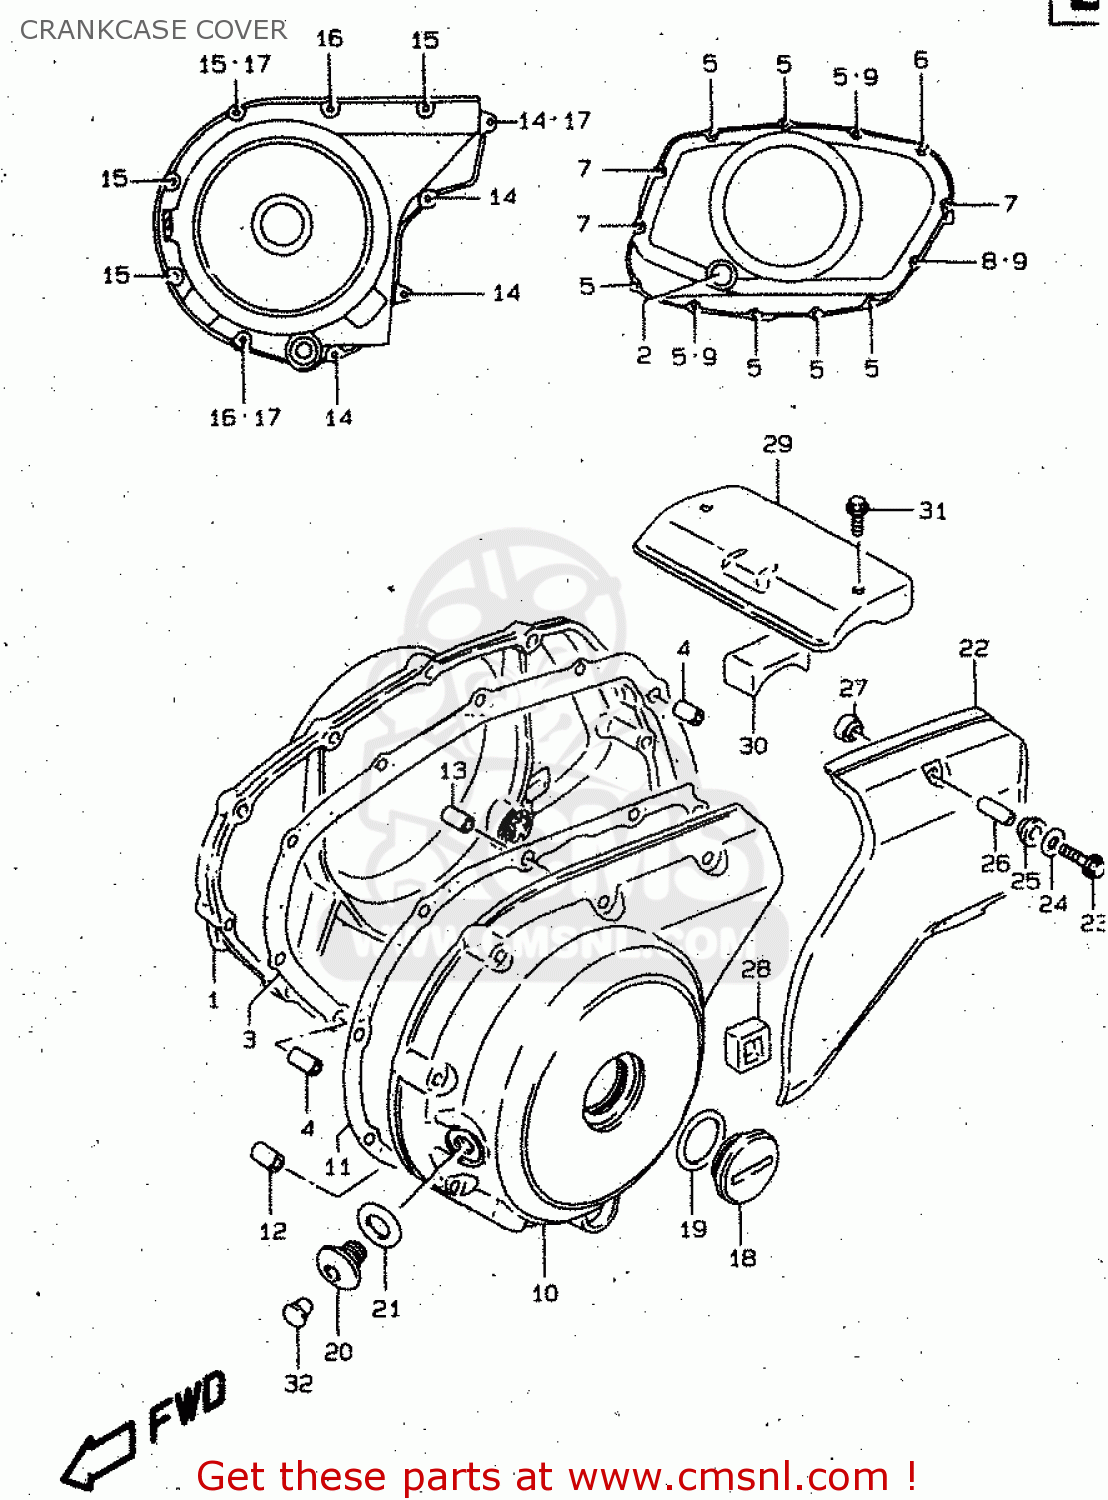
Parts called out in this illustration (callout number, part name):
1	COVER,CLUTCH
2	LENS,OIL LEVEL CHECK
3	GASKET,CLUTCH COVER (NAS)
4	PIN
5	BOLT
6	BOLT
7	BOLT
8	BOLT
9	GASKET(5.8X11X1.2) (NAS)
10	COVER,GENERATOR
11	GASKET,GENERATOR COVER (NAS)
12	PIN(8.4X11X20)
13	PIN
14	BOLT
15	BOLT
16	BOLT
17	GASKET(5.8X11X1.2) (NAS)
18	Chrome Crankshaft Plug
19	O RING(D:3.1,ID:32.7)
20	PLUG,14X12
21	GASKET(13.8X18.8X4.8) (NAS)
22	COVER,SECONDARY GEAR CASE
23	BOLT
24	WASHER(6.5X14X1.6)
25	WASHER(8.7X15X2.1)
26	SPACER(6.5X9X33.3)
27	WASHER(8.7X16X5)
28	DAMPER,SECONDARY COVER
29	COVER,STARTER MOTOR
30	DAMPER,MOTOR COVER
31	BOLT
32	CAP(OD:12)
